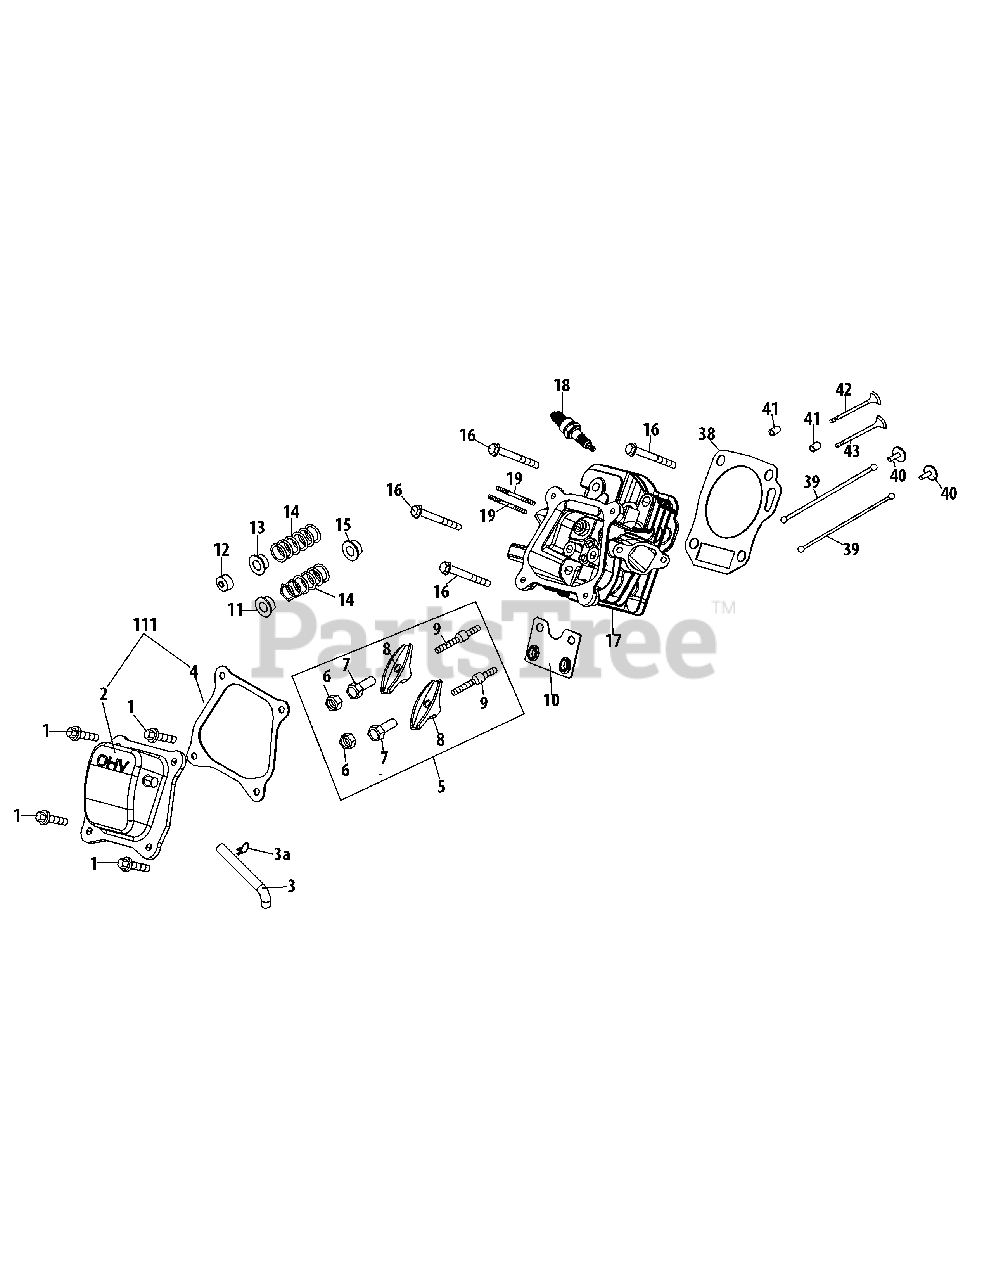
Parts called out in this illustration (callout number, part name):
1	Bolt M6×16
2	Valve Cover
4	Valve Cover Gasket
5	Roker Arm Assembly
6	Nut, Pivot Locking
7	Adjusting Nut, Valve
8	Rocker Arm
9	Bolt, Pivot
10	Push Rod Guide
11	Retainer, In. Valve Spring
12	Adjuster, Ex. Valve
13	Retainer, Ex. Valve Spring
14	Valve Spring
15	Intake Valve Seal
16	Bolt M8×55
17	Cylinder Head Assembly
18	Spark Plug
19	Stud M8×36
19	Muffler Stud Assembly
38	Gasket Cylinder Head
39	Push Rod
40	Tappet
41	Dowel Pin, 10×16
42	Exhaust Valve
43	Intake Valve
111	Valve Cover Kit
